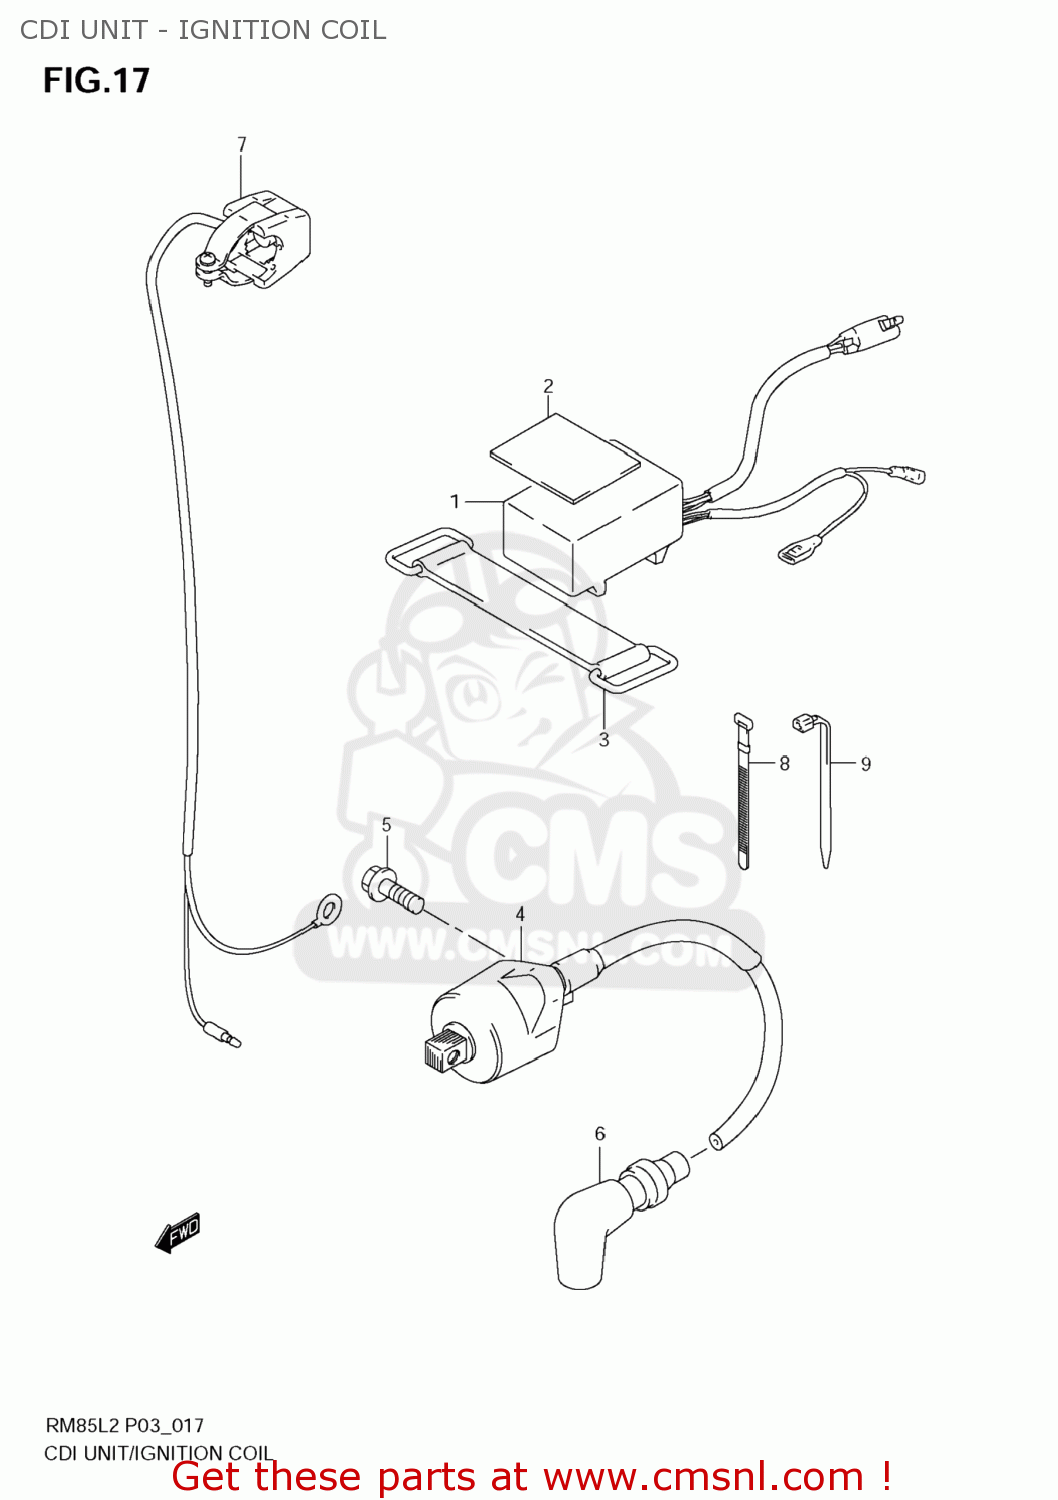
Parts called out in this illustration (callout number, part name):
1	CDI UNIT
2	CUSHION(30X50X3)
3	BAND
4	COIL ASSY,IGNITION
5	BOLT
6	CAP,SPARK PLUG
7	SWITCH ASSY,ENGINE STOP
8	CLAMP(L:120)
9	CLAMP(L:90)
